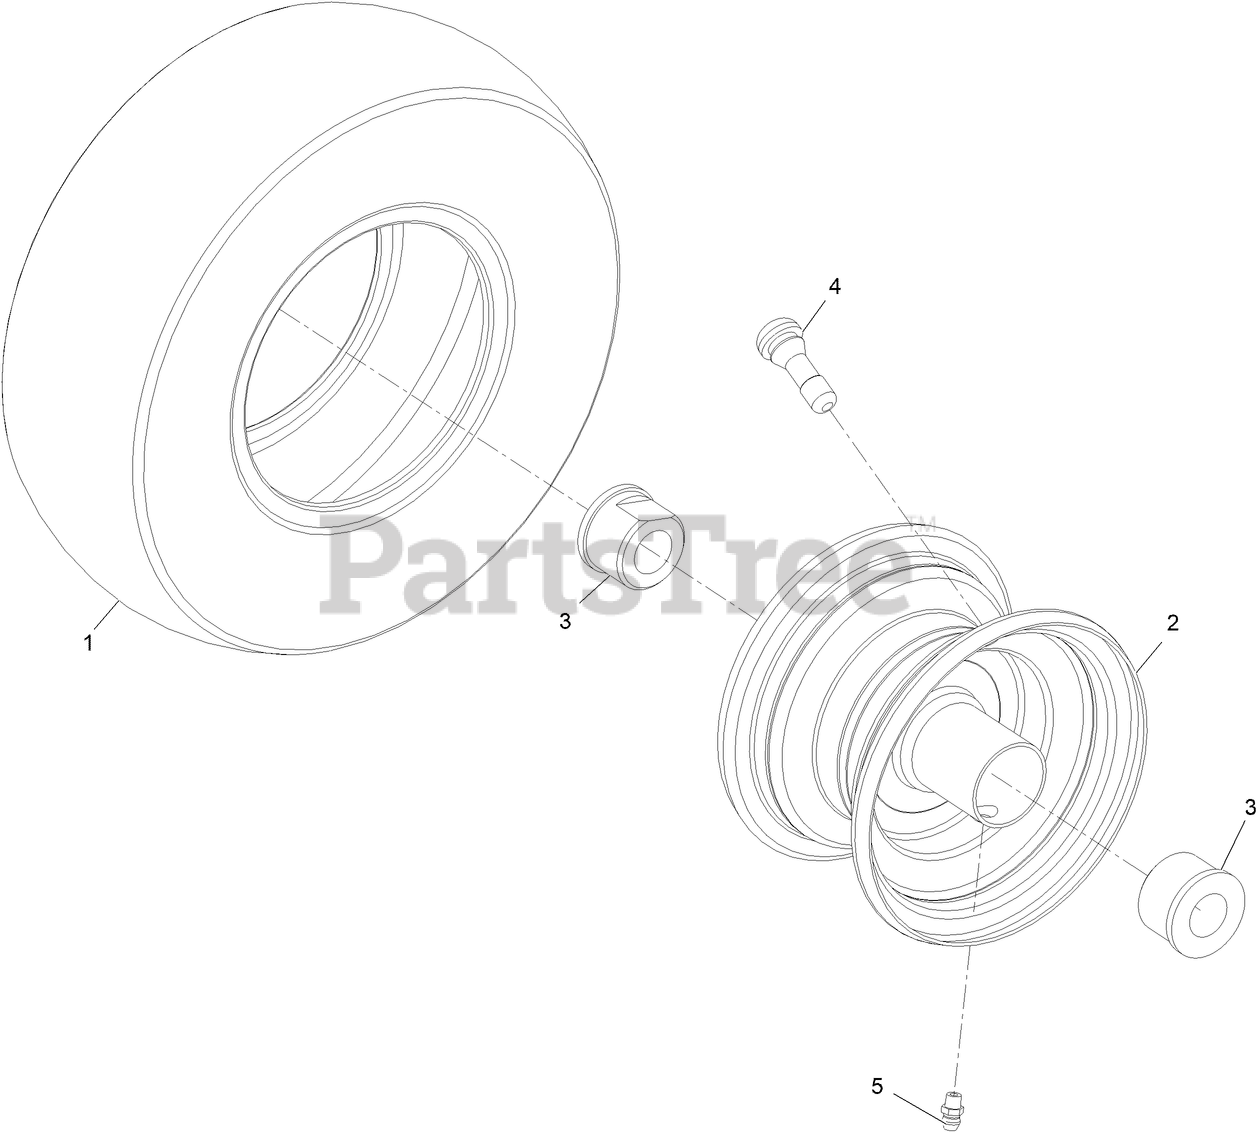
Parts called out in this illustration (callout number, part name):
3	BUSHING-FLANGE
4	Stem-Valve
5	Zerk 1/4-28 Str Thrd Forming
